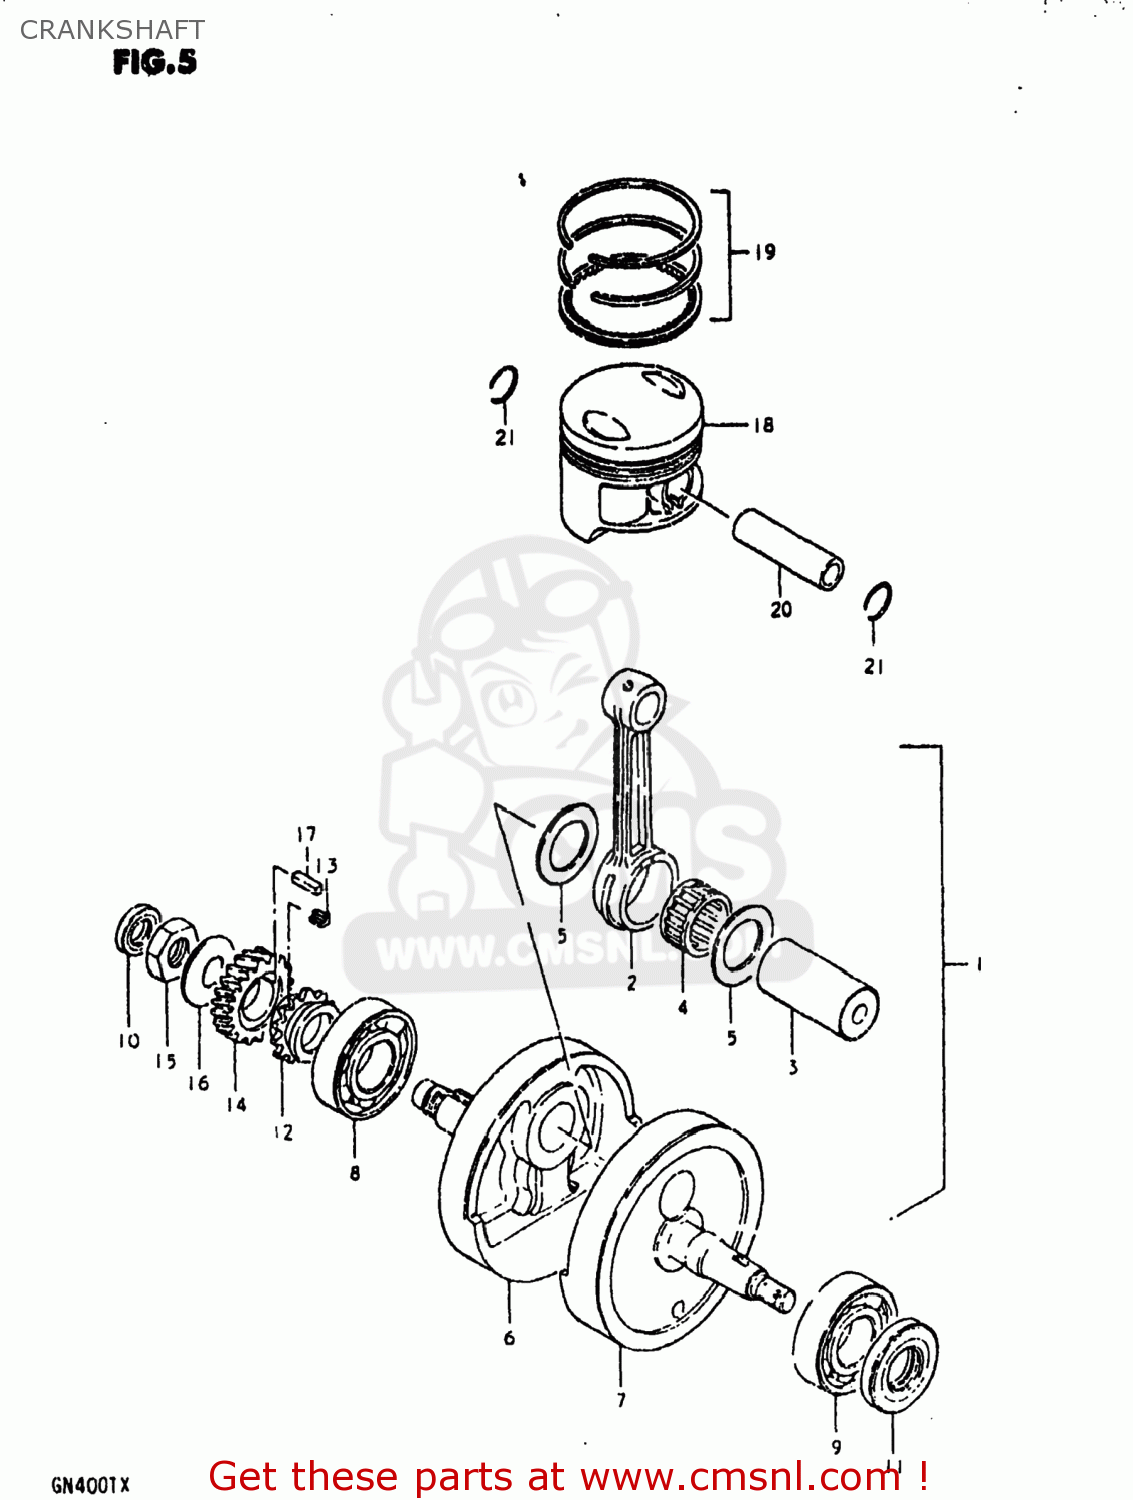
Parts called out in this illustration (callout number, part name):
1	CRANKSHAFT ASSEMBLY
2	ROD,CONNECTING
3	PIN,CRANK
4	BEARING
5	WASHER(34X52X1)
6	CRANKSHAFT
7	CRANKSHAFT,LEFT
8	BALL BEARING 30X72X19
9	BALL BEARING 30X72X19
10	SEAL,OIL(16X30X6)
11	SEAL,OIL(30X58X7)
12	SPROCKET,CAM CHAIN DRIVE
13	KEY,SPROCKET
14	GEAR,PRIMARY DRIVE
15	NUT (20MM)
16	WASHER
17	KEY
18	PISTON
19	RING SET,PISTON
20	PIN,PISTON
21	CIRCLIP
